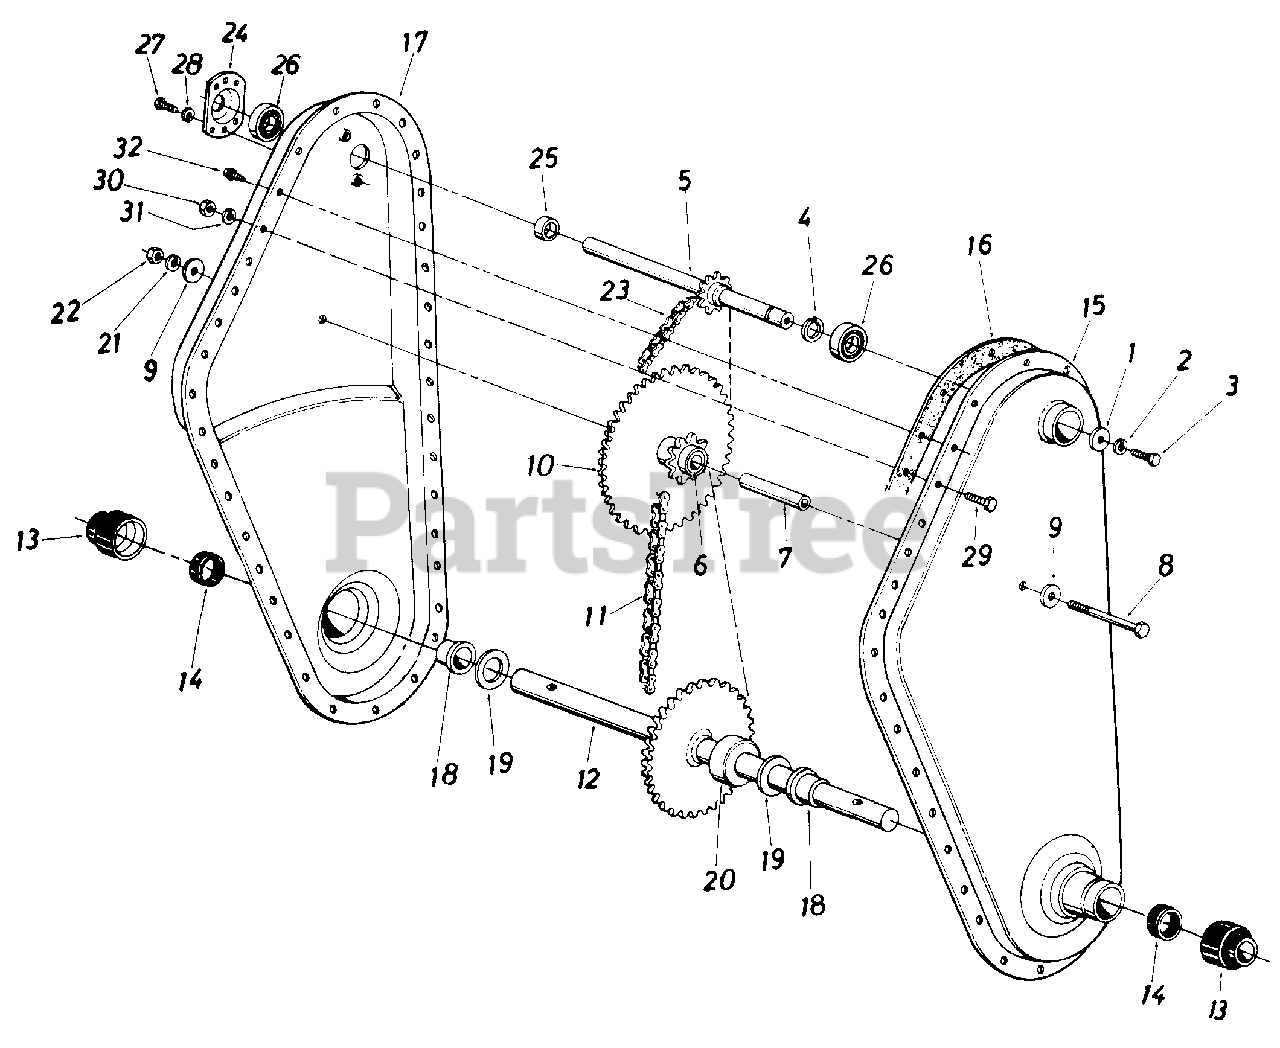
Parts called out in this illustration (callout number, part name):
1	Fl-Wash. 1/4" I.D. x .93n O.D. x .120
2	L-Wash. 1/4" I.D.
3	Hex Bolt 1/4-28 x .62" Lg. w/ Patch
4	External Snap Ring 5/8" Dia.
5	Input Shaft Ass'y.
6	Bearing 5/8" l.D. x 3/4" O.D. x 1.860" Lg.
7	Sprocket Hub Tubing 8/8" l.D. x 5/8" O.D. x 1.90
8	Hex Bolt 3/8-24 x 2.75" Lg.*
9	Fl-Wash. 8/8" l.D. x 1.25" O.D. x .10
10	Sprocket Ass'y.
11	#50 Chain 5/8" Pitch x 46 Links Endless
12	Tine Shaft Ass'y.
13	Dust Cup
14	Seal Ring Single Lip, Springless
19	Fl-Thrust Wash. 1.0" I.D. x .03 Thk.
20	Step Spacer
21	L-Wash. 3/8" I.D.*
22	Hex Nut 3/8-24 Thd.*
23	#35 Chain 3/8" Pitch x 52 Links Endless
24	Bearing Housing 1.38" I.D.
25	Spacer
26	Ball Bearing .625" I.D. x 1.38" O.D. x .437
27	Hex Wash. SF Tap Scr. 1/4-20 x.50" Lg.
28	L-Wash. 1/4" I.D.*
29	Hex Bolt 5/16-18 x .75" Lg.
30	Hex Nut 5/16-18 Thd.
31	L-Wash. 5/16" I.D.
32	Hex Wash. SF-Tap Scr. 1/4-20 x 50" Lg
